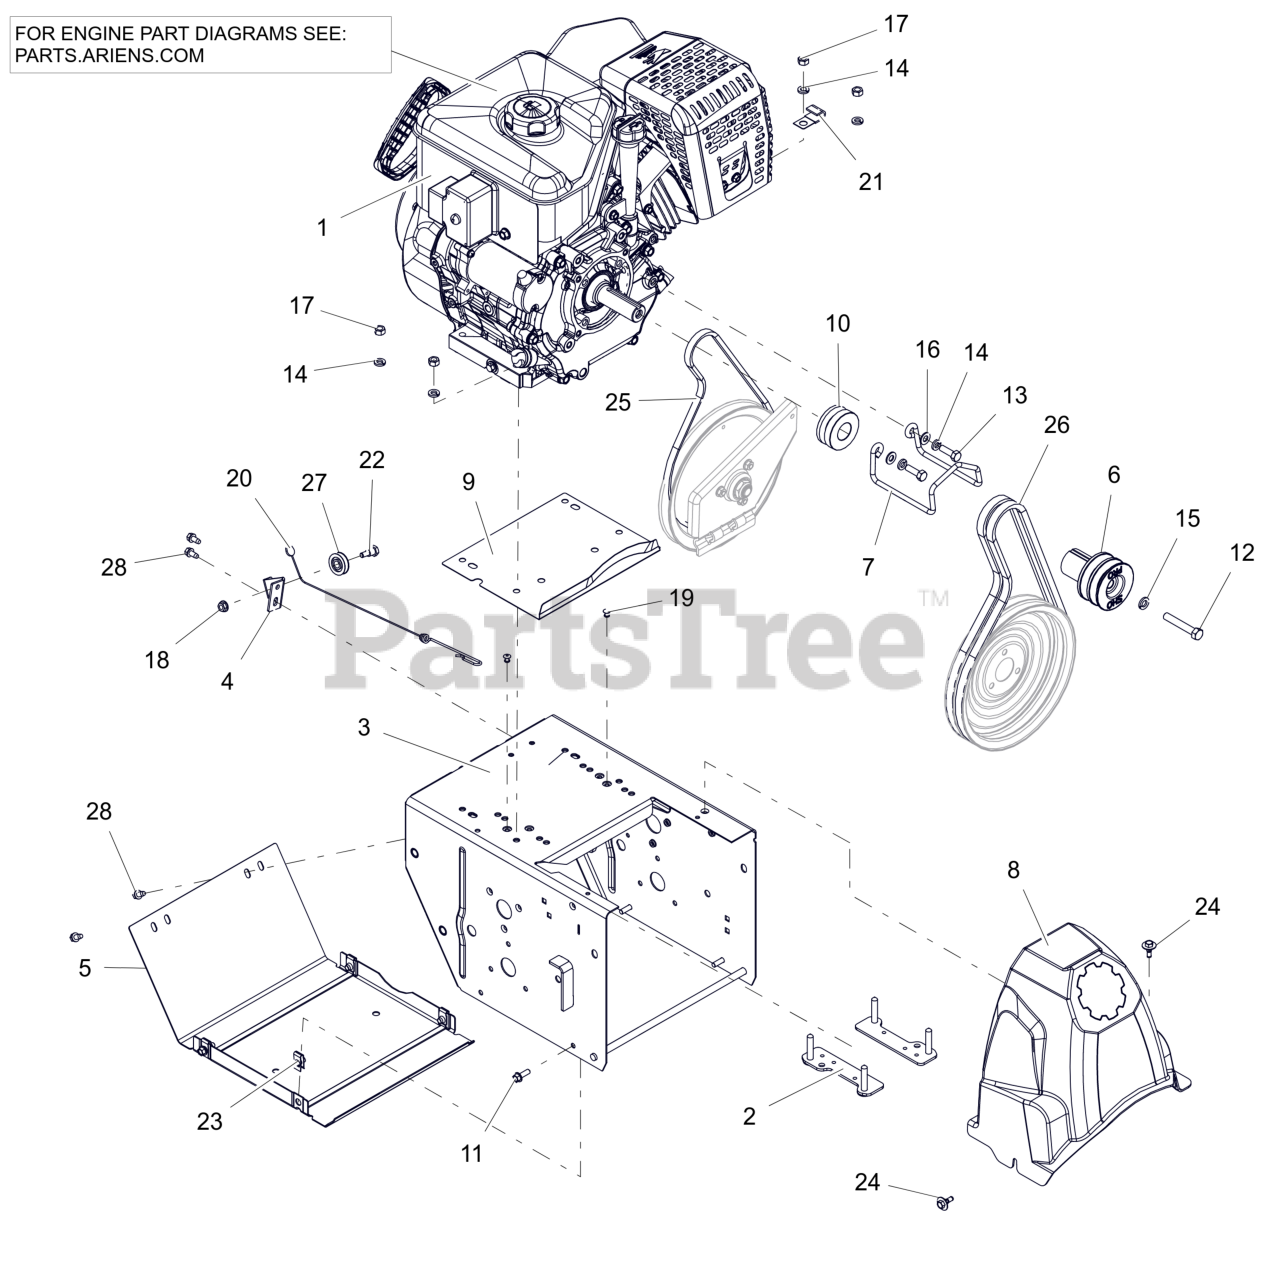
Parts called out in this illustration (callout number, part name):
1	ENGINE, EFI 369 GEN 3 240V/60W
2	STRAP, BOLT-LARGE
3	FRAME, MAIN - 14GA DELUXE (ORANGE)
4	BRKT, CABLE PULLEY
5	COVER, BOTTOM
6	SHEAVE,ATTACHMENT-SHO 2 GRV
7	FINGER, BELT
8	COVER, BELT
9	BAFFLE, WATER - LARGE BLOCK
10	SHEAVE, TRACTION (KEYLESS)
11	BLT, HWH .25-20X.75 G5 ZCC
12	BLT, HEX .38-24X2.25 G5 ZCC
13	BLT, HEX 0.3125-24X1 G5 ZCC
14	WSHR, LK-HVY .312X.097 ZCC
15	WSHR,LK-REG .375X.094 ZCC
16	WSHR,FLT .344X.688X.065 ZCC
17	NUT, HEX .312-18 ZCC
18	NUT-LK-TOP-FLG .250-20 GF ZCC
19	RVT, POP .1875 ZCC
20	CABLE, LOWER TRACTION,SS & PRO
21	J-CLAMP
22	BOLT, SHLDR -.375 X .375 X .25-20
23	NUT-RTNR .25-20X.56
24	SCR-TAP .25-20X.5 CAPTIVE
25	V-BELT, 3L-WRAPPED
26	V-BELT, HA-RAW EDGE (SET)
27	PULLEY, CABLE
28	SCR-TAP .25-20X.50 HWH ZCC
